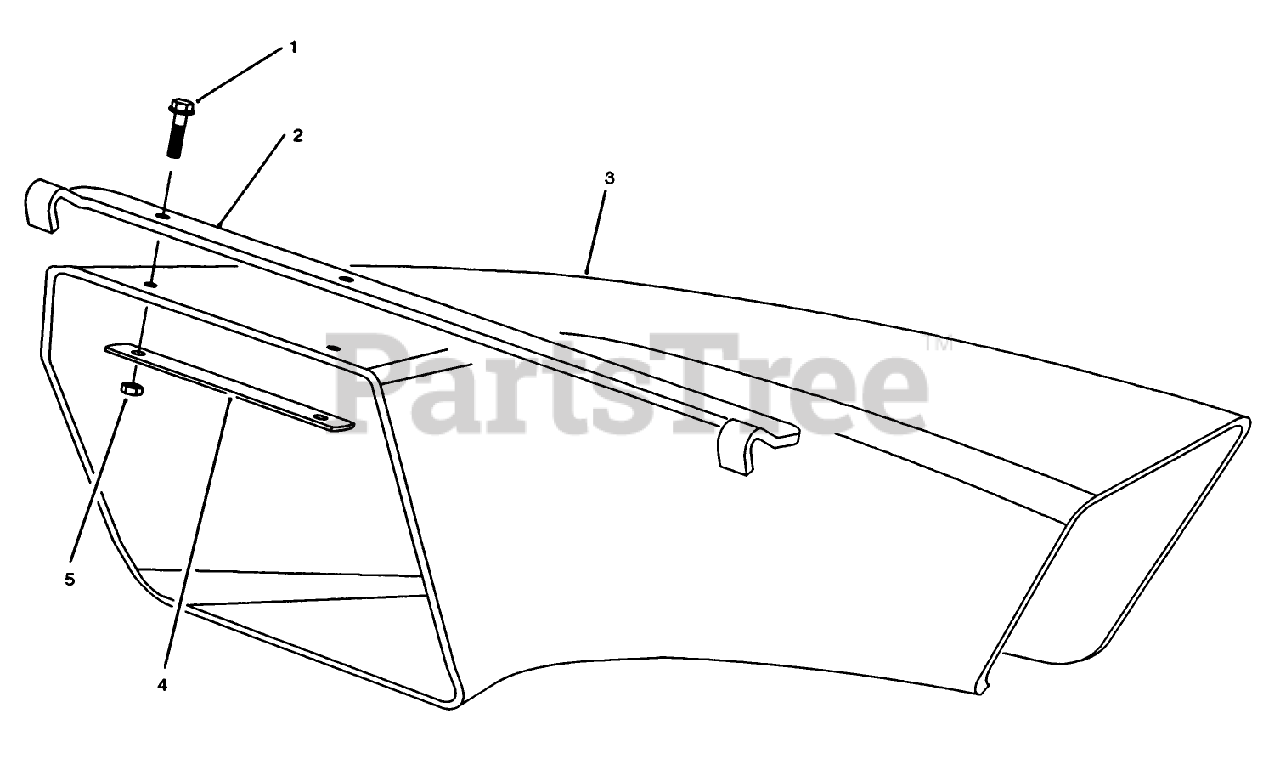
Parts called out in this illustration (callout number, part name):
1	SCREW-HWH
2	CHUTE HANGER BRACKET*
4	NUT-LOCK, NI
